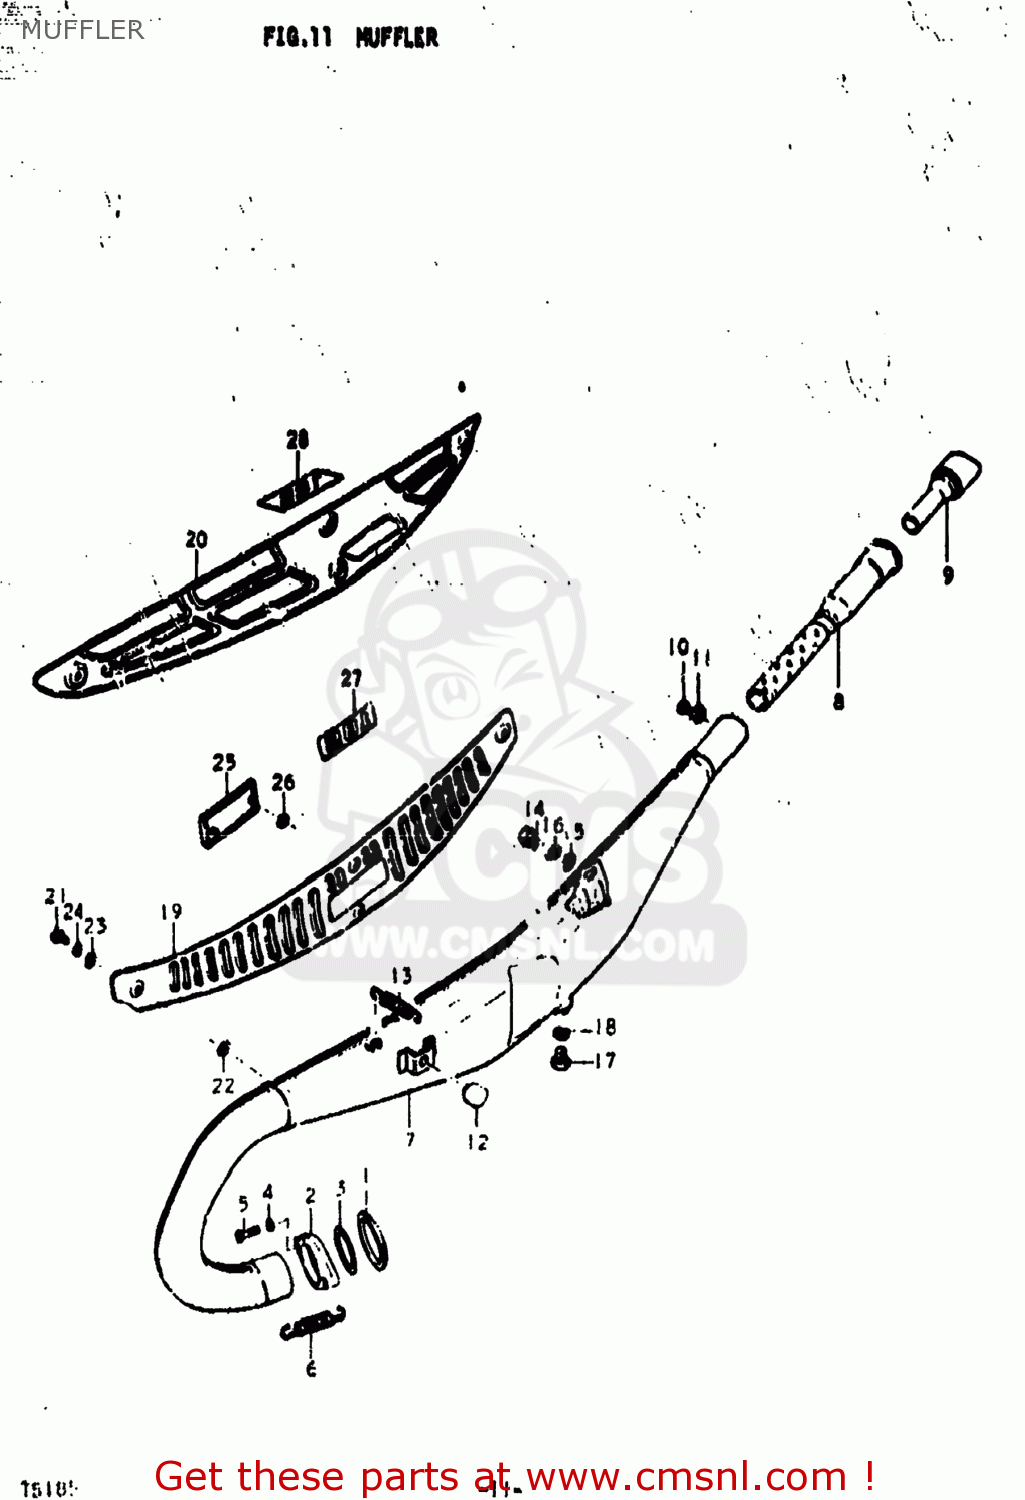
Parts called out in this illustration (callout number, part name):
1	GASKET,EXHAUST PIPE (NAS)
2	CLAMP,EXHAUST PIPE
3	CUSHION,EXHAUST PIPE
4	LOCK WASHER
5	BOLT
6	SPRING
7	MUFFLER ASSEMBLY
8	ARRESTER,SPARK
9	TUBE,MUFFLER CLEAN OUT
10	SCREW
11	LOCK WASHER
12	CUSHION(11.5X22X20)
13	SPRING
14	BOLT
15	WASHER (8.5X18X2)
16	LOCK WASHER
17	BOLT 10X9
18	GASKET(10X14X3.6) (NAS)
19	COVER,MUFFLER
20	COVER,MUFFLER
21	SCREW
22	GASKET 6.2X12X1.5 (MCA)
23	WASHER 6MM
24	LOCK WASHER
25	EMBLEM,MUFFLER COVER
26	NUT
27	EMBLEM,MUFFLER COVER
28	EMBLEM,MUFFLER COVER
